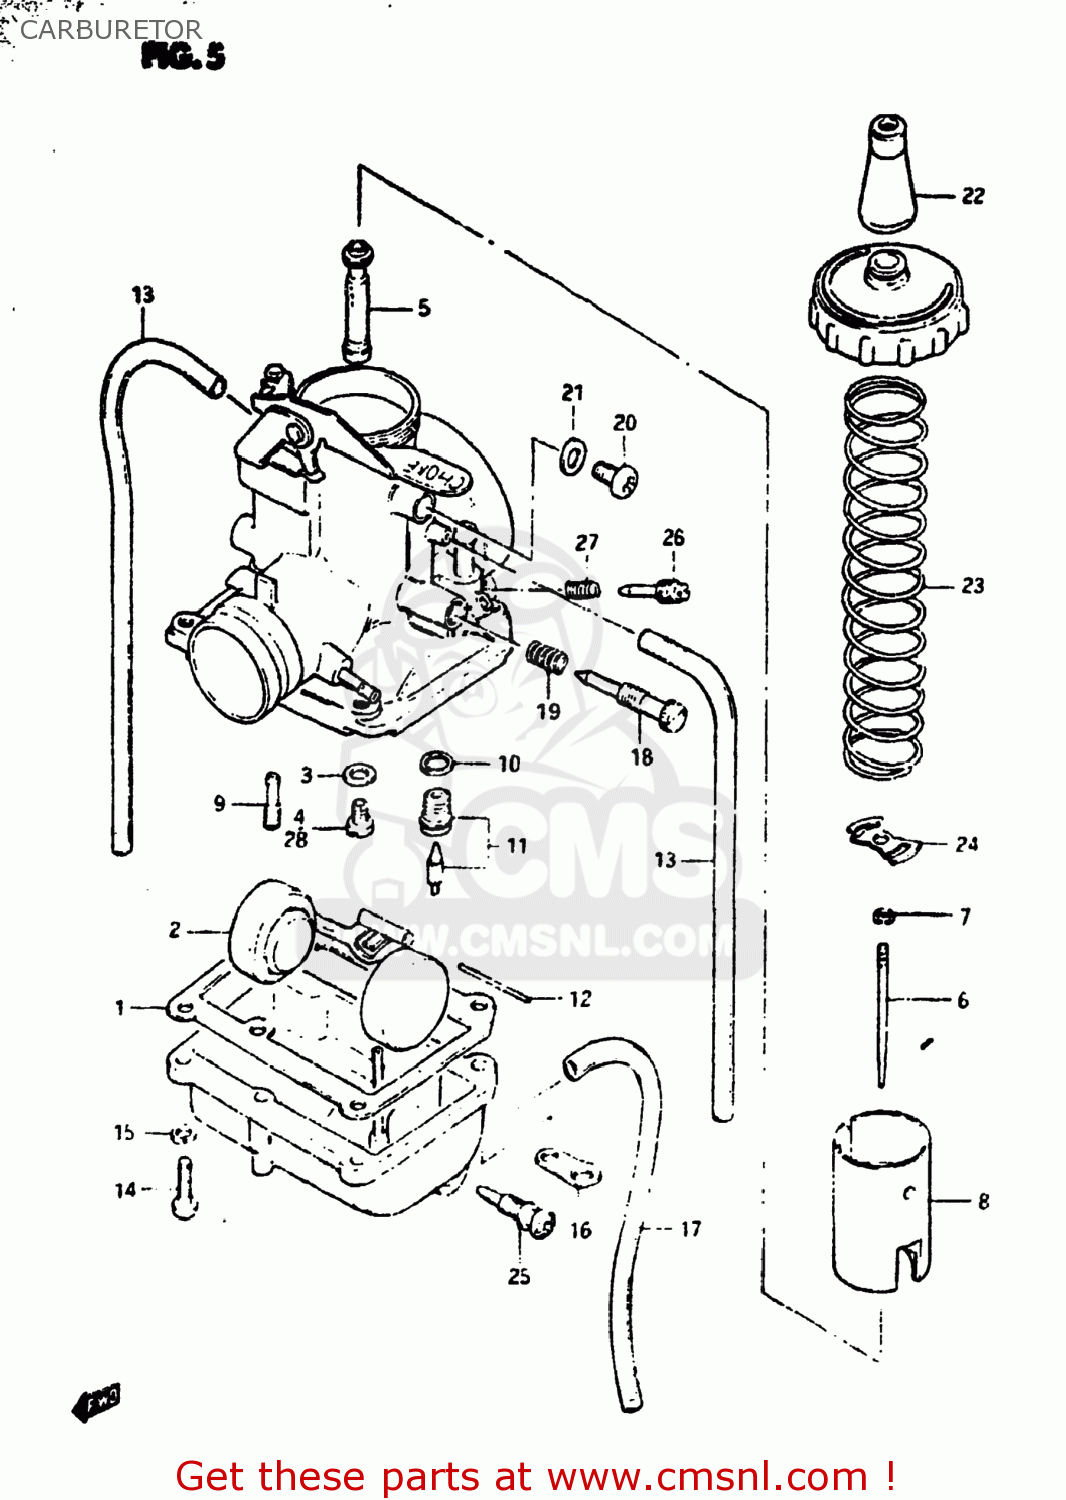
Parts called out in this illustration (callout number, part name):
1	GASKET,FLOAT CHAMBER (NAS)
2	FLOAT
3	WASHER,NEEDLE NOZZLE
4	JET
5	JET,NEEDLE
6	NEEDLE,JET
7	CLIP
8	VALVE,THROTTLE
9	JET,PILOT(25)
10	GASKET,NEEDLE VALVE (NAS)
11	VALVE ASSY,NEEDLE
12	PIN,FLOAT
13	HOSE
14	SCREW
15	LOCK WASHER
16	PLATE
17	HOSE
18	SCREW,THROTTLE STOP
19	SPRING
20	SCREW
21	GASKET,DRAIN PLUG (NAS)
22	CAP,CABLE ADJUSTER
23	SPRING,THROTTLE VALVE
24	STOPPER,NEEDLE CLIP
25	PLUG,DRAIN
26	SCREW,PILOT AIR
27	SPRING
28	JET
